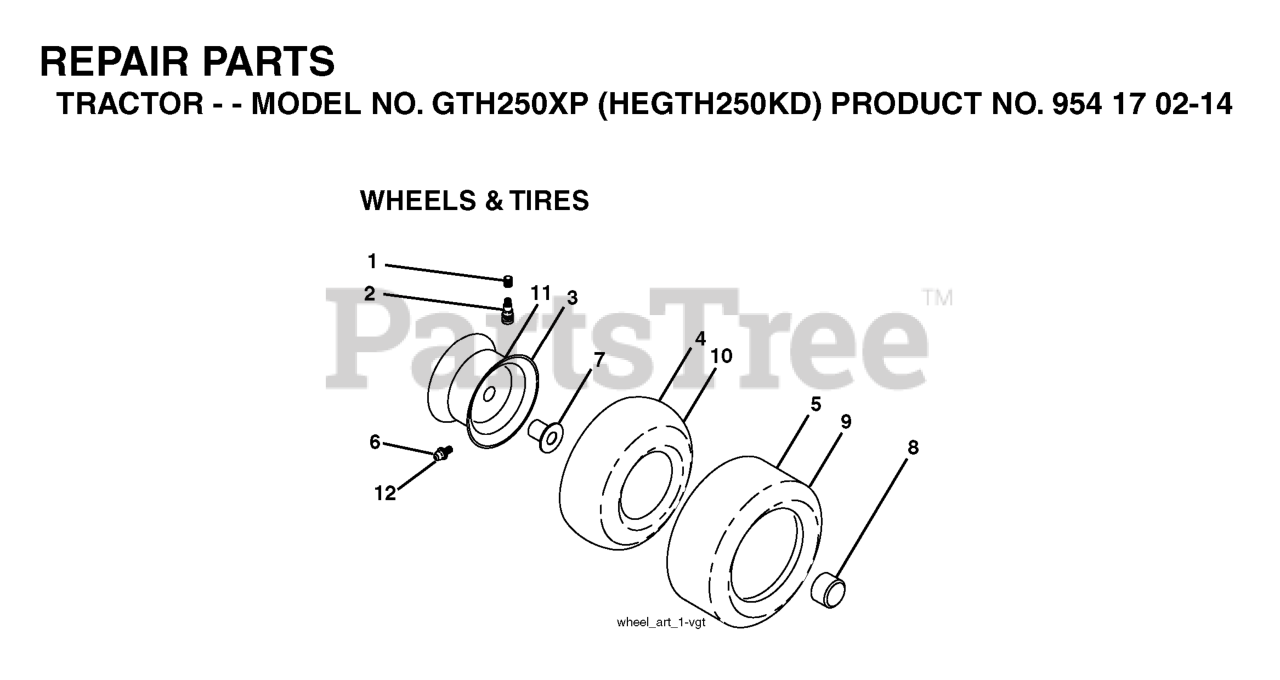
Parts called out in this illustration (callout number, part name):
2	VALVE STEM LT
3	RIM ASSEMBLY, FRONT
4	TUBE.16X6.5/7.5-8
5	TIRE HEAVY DUTY
6	FITTING LT
7	BEARING T
8	CAP, AXLE BLK
9	TIRE HEAVY DUTY
10	TUBE.23X9.5-12
11	RIM.ASM.12X7.REAR.SILVER
12	ZERK FITTING M
